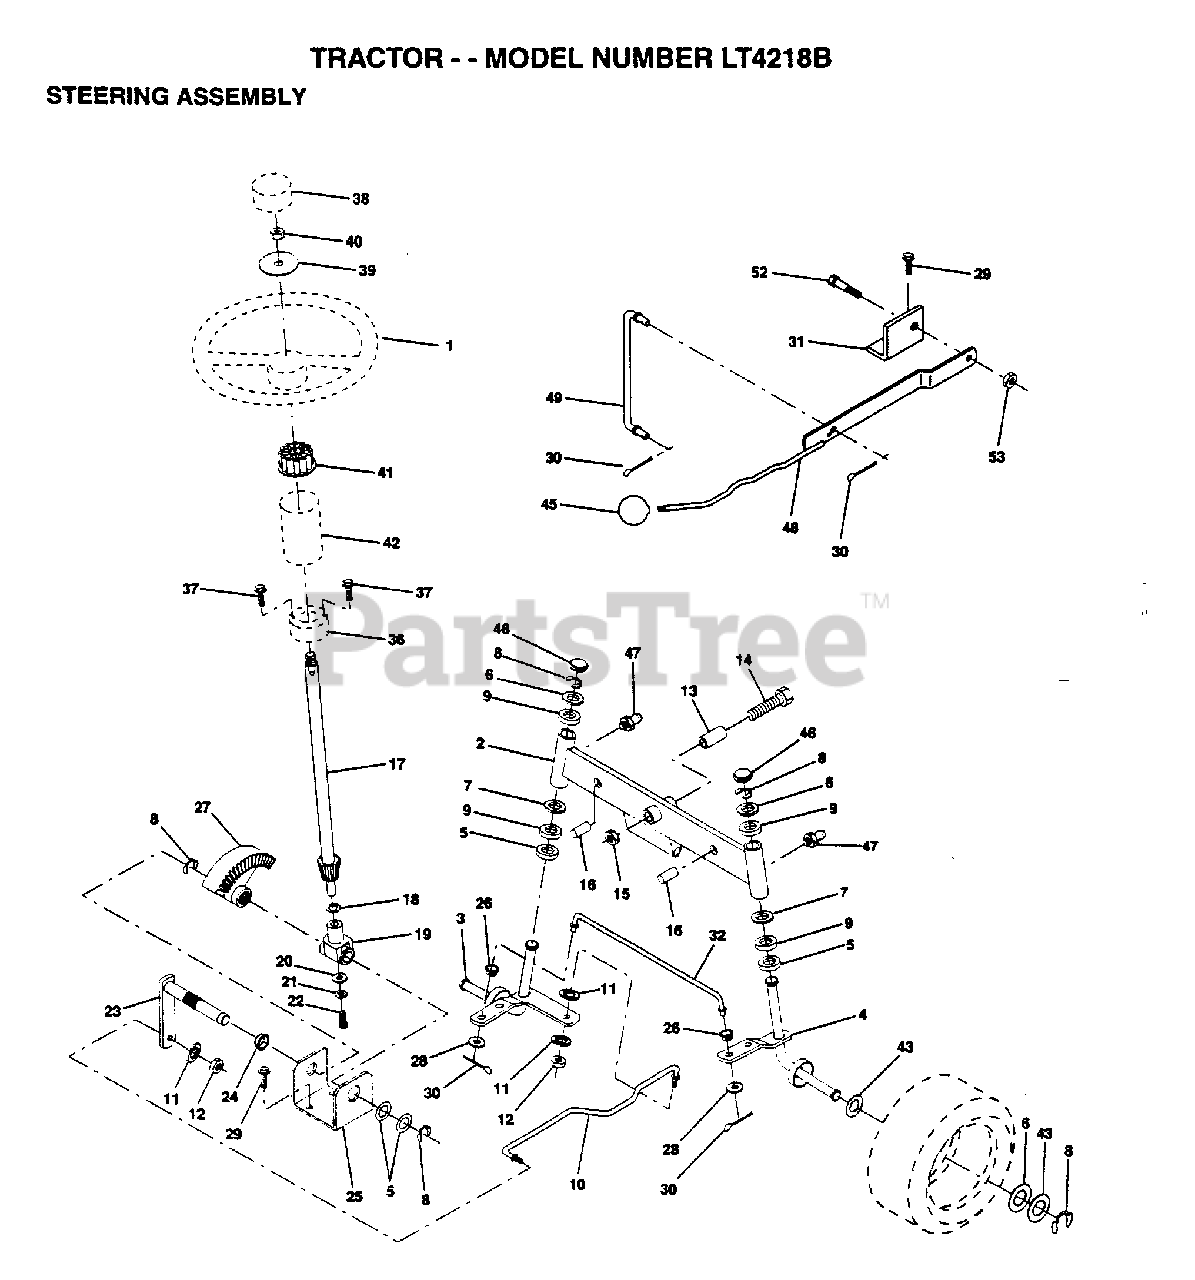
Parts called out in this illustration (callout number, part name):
2	AXLE ASM FRONT
3	SPINDLE LH
4	SPINDLE RH
5	WASHER .T
6	WASHER
7	WASHER
8	RING
9	COL. SRTG. BEAR.
11	LOCKWASHER
13	BEARING
14	BOLT HEX 5/8-11
15	"NUT-LOC,FLANGE LT"
16	AXLE PIN
17	SHAFT&GEAR STR T
18	THRUST WASHER
19	SUPPORT.SHAFT
21	LOCKWASHER
22	"SCREW,SPECIAL"
24	NYLINER T
25	"BRKT,STEERING"
27	GEAR SECTOR
28	WASHER
29	SCREW
30	COTTER PIN
31	BRKT.PVT.MAN.LVR.
32	TIE ROD
38	ST WHL INSERT CAP
39	WASHER
41	ADAPTER LT
43	WASHER
45	KNOB T (1/2-HOLE)
46	CAP
47	ZERK M
48	LEVER ASSY T
49	LINK CLTCH W/NUTS
50	COTTER PIN
52	"BOLT, SHOULDER LT"
